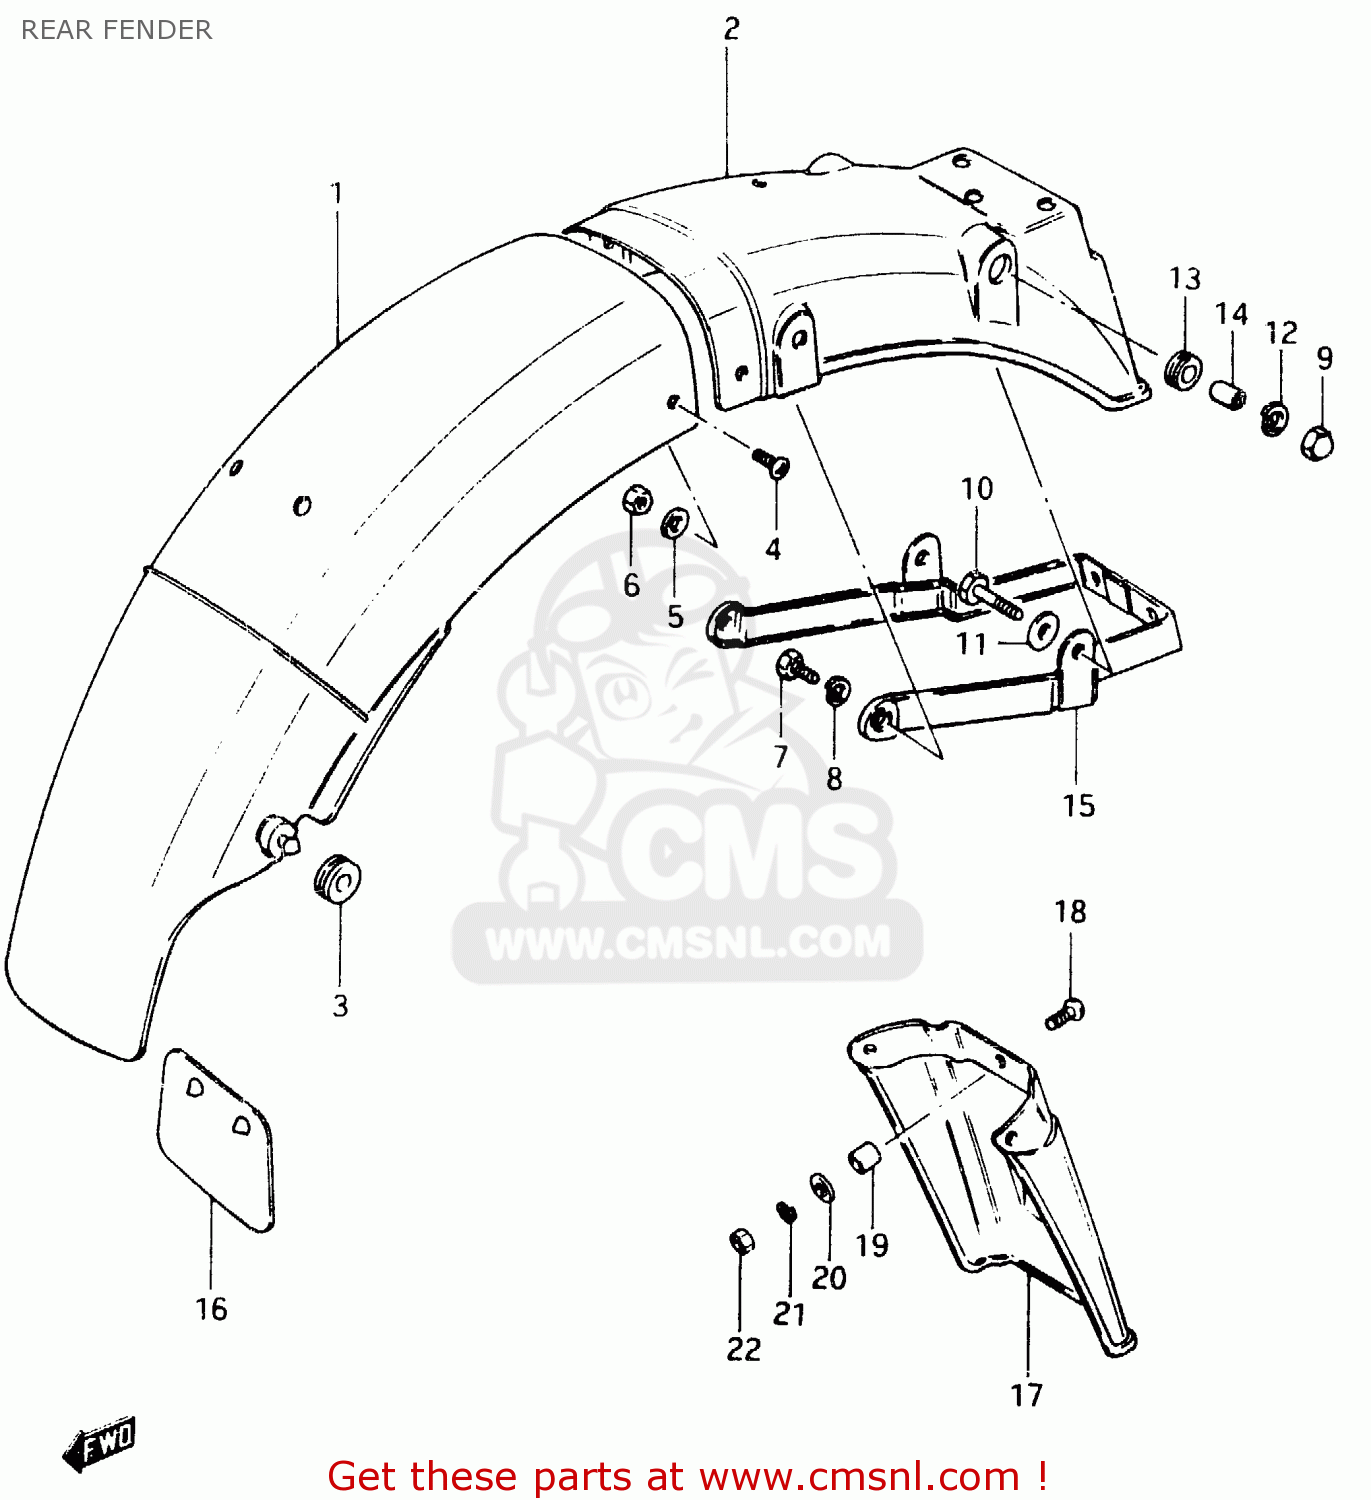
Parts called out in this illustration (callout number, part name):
1	BODY,RR FENDER FR
2	BODY, REAR FENDER REAR
3	CUSHION
4	SCREW
5	WASHER (5.5X16X1.2)
6	NUT
7	BOLT, UPPER
8	LOCK WASHER
9	NUT
10	BOLT
11	WASHER
12	LOCK WASHER
13	CUSHION
14	SPACER (8.2X12X7.5)
15	REINFORCEMENT, REAR FENDER
16	GUIDE,RR FENDER MUD
17	EXTENSION, REAR FENDER
18	SCREW (6X15)
19	SPACER(6.2X8.3X5.7)
20	WASHER(6.5X18X1)
21	LOCK WASHER
22	NUT
